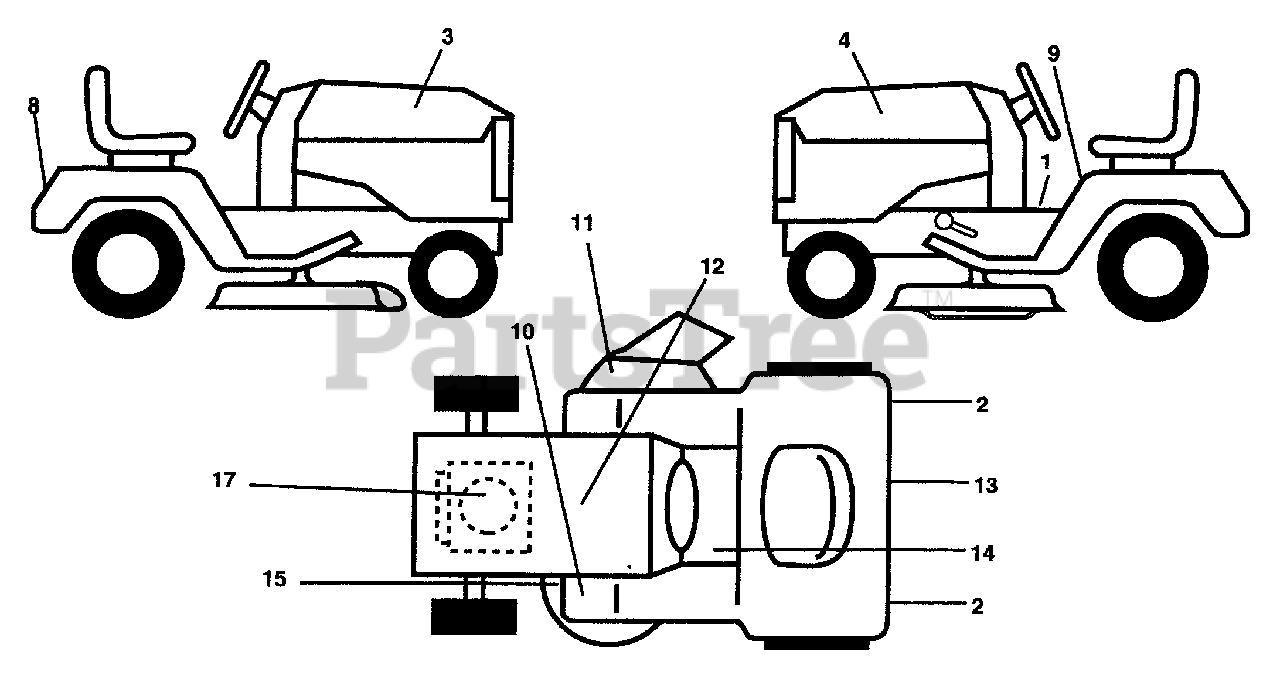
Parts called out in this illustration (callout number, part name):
1	Decal Instruction Dash Eng/fr
2	Reflector Taillight Red/Ambus
3	Decal Hood RH
4	Decal Hood LH
8	Decal Fender Logo
9	Decal Caution Fender Eng/fr
10	Decal Clutch/brake Eng/fr
11	Decal Warning Multi-Language
12	Decal Bat Dan/Poi P/L Sym WPN
13	Decal Drawbar CNTRL MVT HYD LT
14	Decal SDL COLD START HYD E/F
15	Decal V-Belt Schematic
17	Decal Engine Kohler 15 HP
